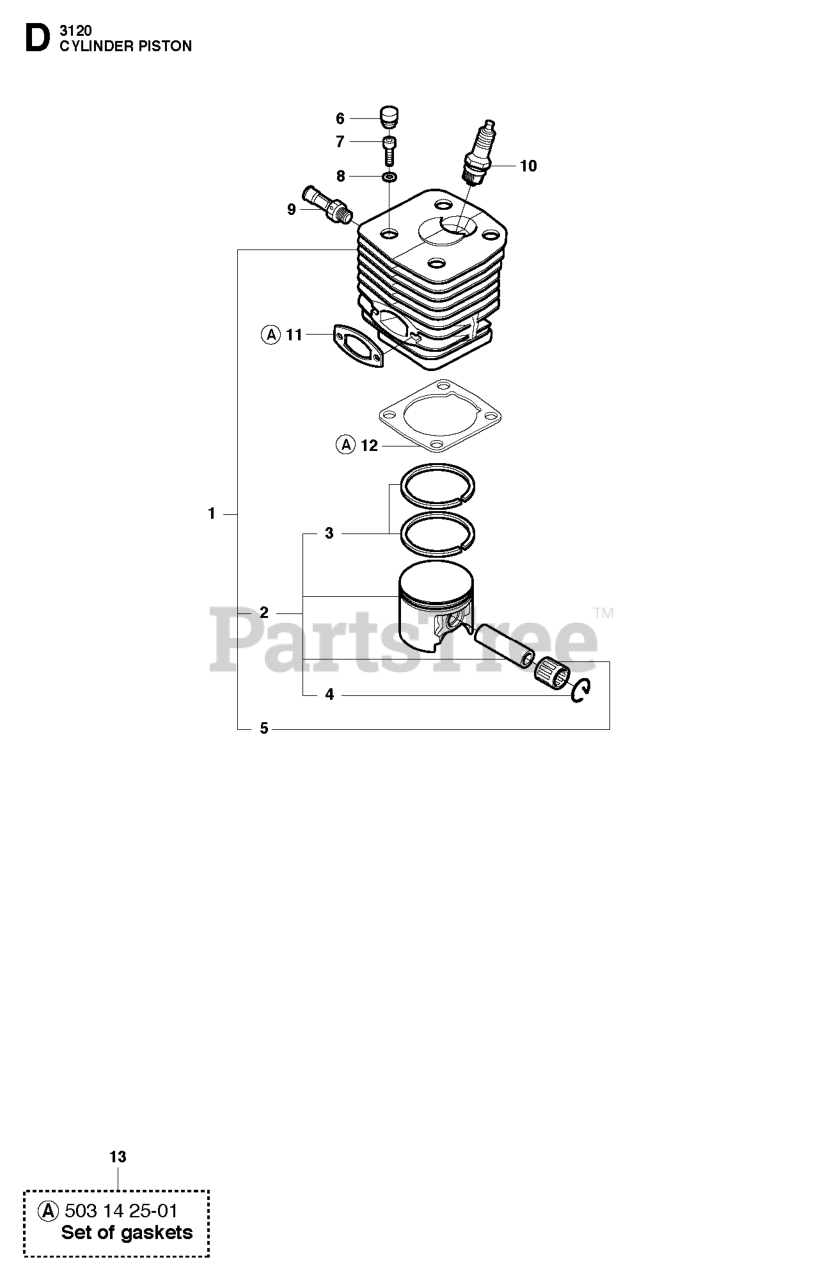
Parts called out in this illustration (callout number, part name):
1	CYLINDER ASSY
2	PISTON CPL
3	PISTON RING
5	SUPPORT BUSHING
6	RUBBER BUMPER
8	WASHER 6.5X11
10	SPARK PLUG RCJ7Y
13	GASKET SET
